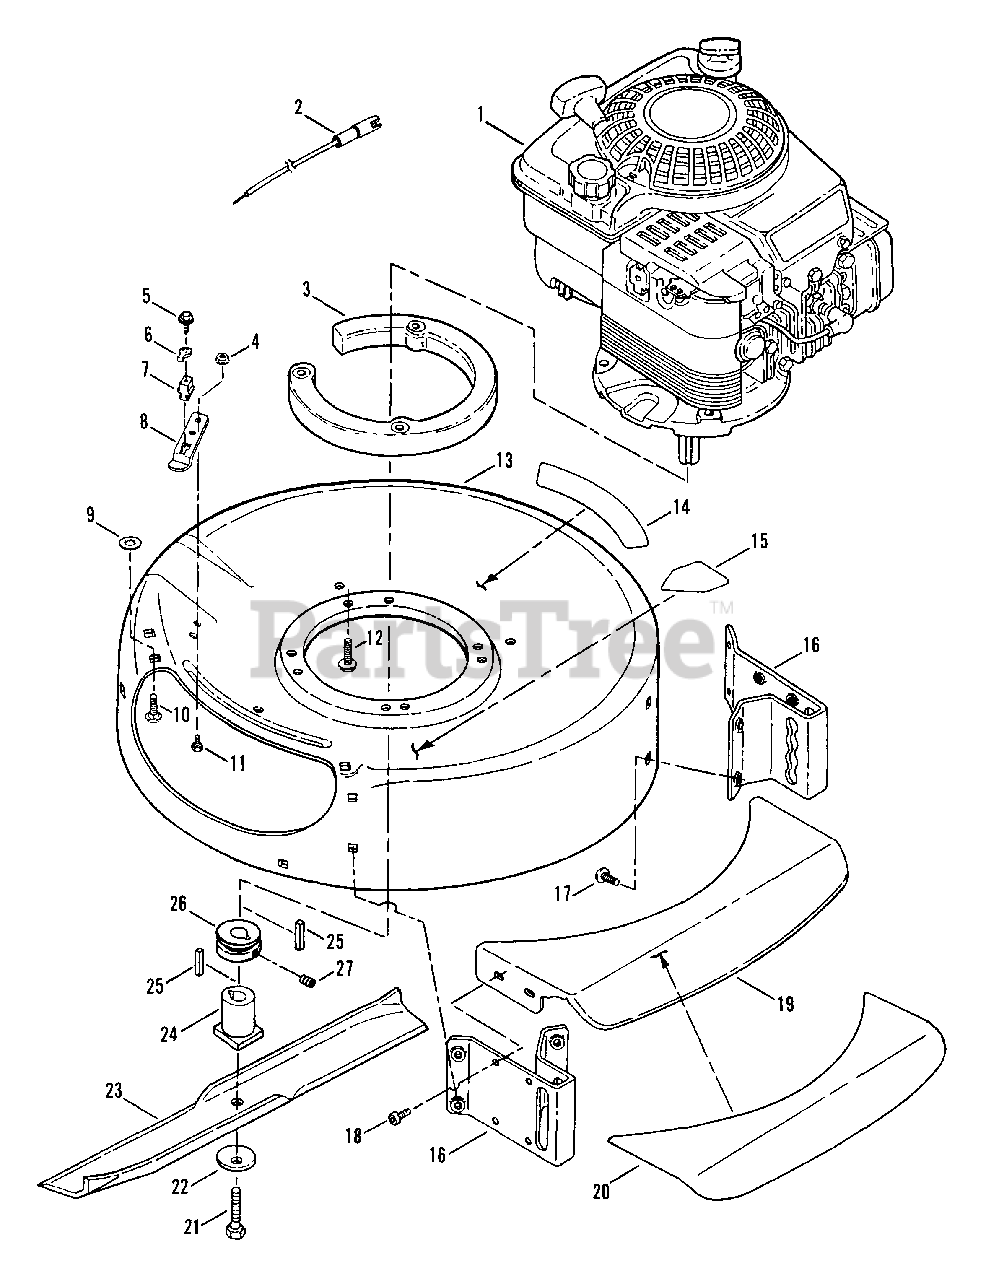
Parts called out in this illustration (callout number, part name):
2	WIRE, Ground
3	RING, Engine Mount
4	NUT, 1/4-20 Hex Flange Lock
5	SCREW, #8-18 x 3/4" Hex Washer Head
6	WASHER, #8 Tab InternaI Tooth Lock
7	INSULATOR
8	SPRING, Interlock
9	RETAINER, 5/16 Bolt
10	BOLT, 5/16-18 x 3/4" Short Neck Carriage, Grade 5
11	SCREW, 1/4-20 Hex Head Cap, Grade 5
12	SCREW, 3/8-16 x 2" Hex Washer Head, Self-Tapping
13	DECK, 20" Cutting
14	DECAL - WARNING
15	DECAL - DANGER (Keep Hands & Feet Away)
16	BRACKET, Front Wheels
17	SCREW, 5/16-18 x 1/2" Pan Head Torx, Self-Tapping
18	SCREW, #10-24 x 1/2" Hex Washer Self-Tap (Torx)
19	PLATE, Deck Front
20	DECAL, "Whipper" SNAPPER
21	SCREW, 3/8-24 x 2" Hex Head Cap, Grade 5
22	WASHER, Cone
23	BLADE, Mulching
24	HUB, Blade
25	KEY, #505 HI-PRO
26	PULLEY, .88 x 2.12" O.D.
27	SCREW, 5/16-18 x 5/16" Hex Socket Set
